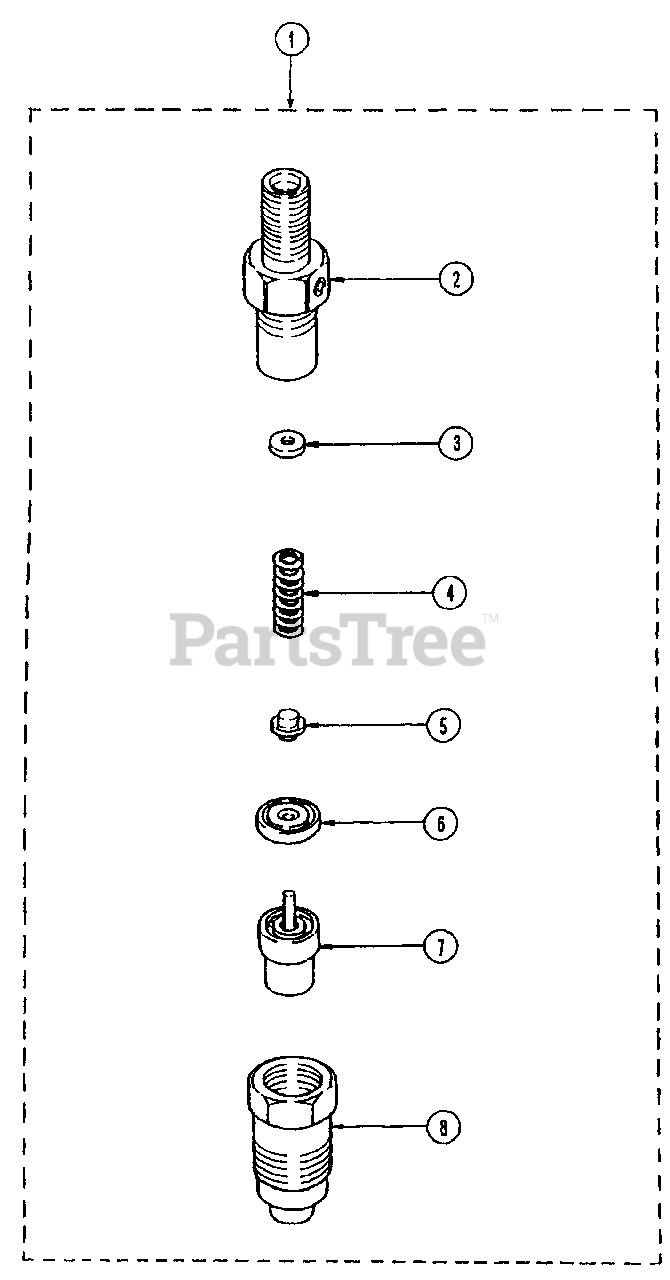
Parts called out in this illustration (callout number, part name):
1	Nozzle & Holder Ass'y
2	Body Sub Ass'y.
3	Washer
4	Spring, Pressure
5	Pin, Pressure
6	Piece, Distance
7	Nozzle Ass'y.
8	Nut, Retaining
